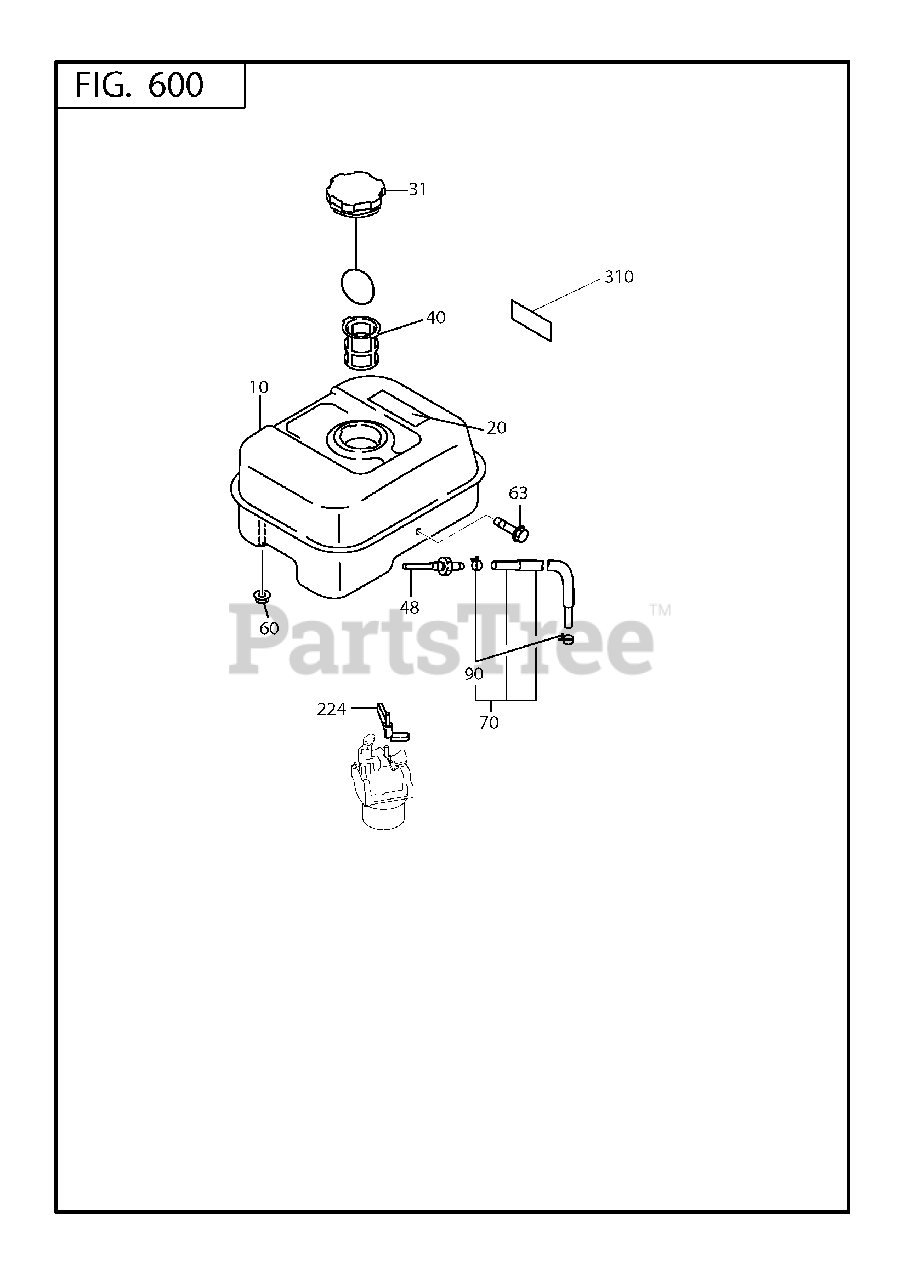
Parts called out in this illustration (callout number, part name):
20	LABEL, WARNING
31	FUEL TANK CAP CP
224	CHOKE LEVER CP
